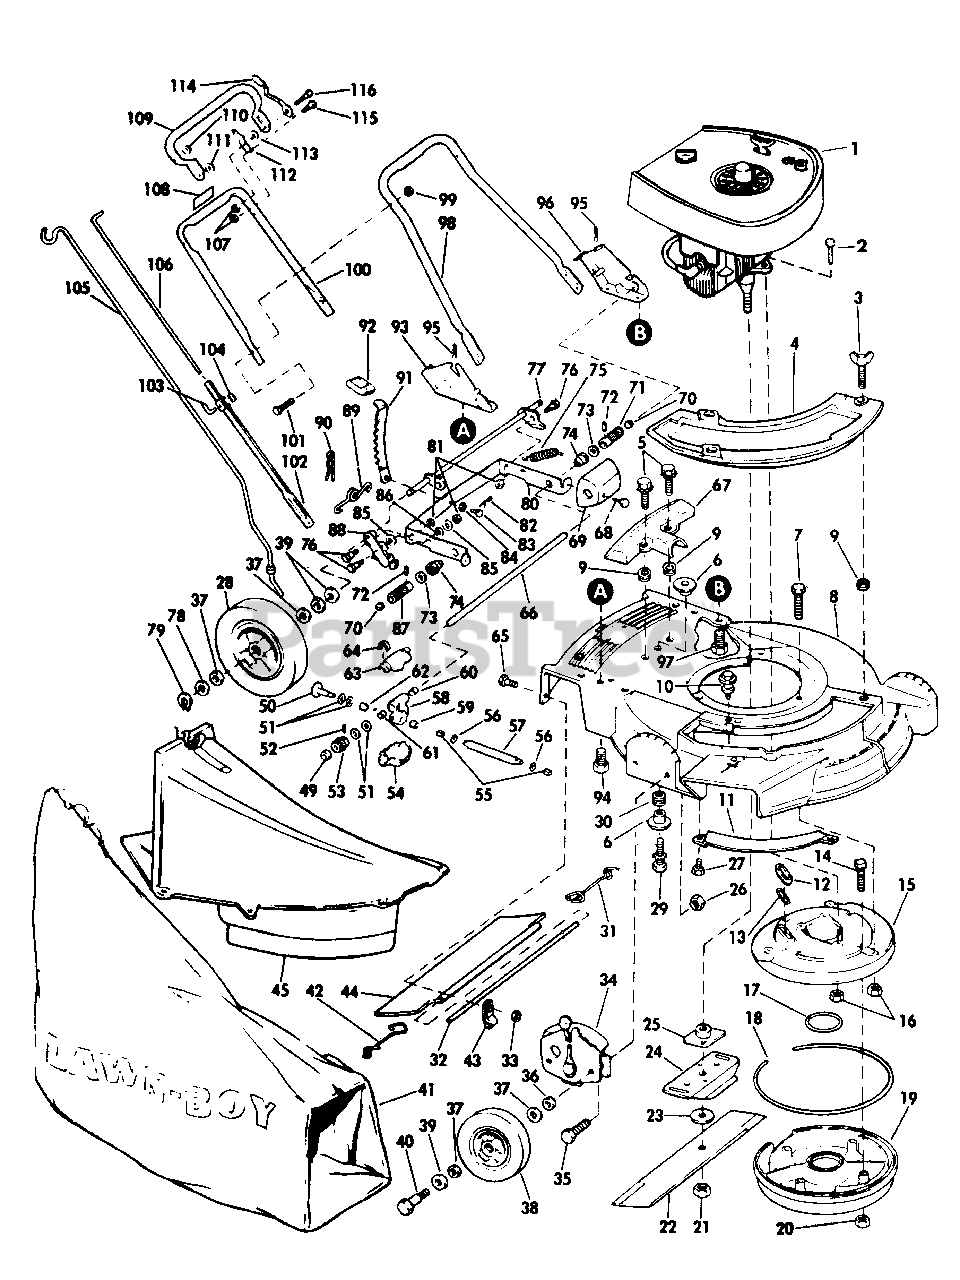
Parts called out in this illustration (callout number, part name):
2	Screw-Crankcase to Muffler Plate
3	Wing Screw
4	Cover Plate
5	Sems Screw-Drive Cover Mounting
6	Spacer-Flanged
7	Screw-Muffler Plate to Housing
8	Housing-21"
9	Grommet
10	Screw
11	Toe Bar
12	Sleeve-Muffler Gasket
13	Gasket-Exhaust
14	Screw-Muffler to Muffler Plate
15	Muffler Plate
16	Nut
17	Gasket-Muffler (inside)
18	Gasket-Muffler (outside)
19	Muffler Cover
20	Nut-Muffler to Muffler Plate
21	Nut-Blade
22	Blade
23	Washer-Blade
24	Stiffener-Blade
25	Collar & Plate Assembly
26	Nut
27	Screw
28	Wheel-Rear
29	Sems Screw
30	Grommet
31	Spring-L.H.
32	Rod
33	Nut
34	Height Adjustment Assembly
35	Screw
36	Washer
37	Washer-Felt
38	Front Wheel
39	Washer
40	Screw
41	Grass Bag
42	Spring-R.H.
43	Clamp
44	Shield Trailing
45	Chute Assembly
49	Washer-Felt
50	Gear-Driver
51	Washer-Thrust
52	Roll Pin
53	Gear-Drive
54	Cover-Gear Bottom
55	Bushing
56	"O" Ring
57	Tube
58	Bracket & Bearing Assembly
59	Needle Bearing-Sealed
60	Needle Bearing-Sealed
61	Needle Bearing
62	Needle Bearing
63	Cover-Gear Top
64	Clamp
65	Screw
66	Shaft
67	Cover-Drive
68	Screw
69	Guard-Roller
70	Plug
71	Drive Roller-L.H.
72	Pin-Spirol
73	Washer
74	Sleeve & Bearing Assembly
75	Spring
76	Bolt-Shoulder
77	Axle Assembly
78	Washer
79	Retaining Ring
80	Bracket
81	Nut
82	Cotter Pin
83	Pin
84	Washer
85	Washer
86	Washer
87	Drive Roller-R.H.
88	Clutch
89	Spring
90	Hairpin
91	Lever
92	Knob
93	Bracket-Handle-R.H.
94	Screw-Handle Bracket
95	Clip
96	Bracket-Handle-L.H.
97	Screw-Handle Bracket
98	Handle-Lower
99	Nut
100	Handle-Center
101	Screw
102	Control Lever Assembly
103	Screw
104	Nut
105	Rod-Grass Bag
106	Control Rod
107	Nut
108	Decal
109	Handle & Grip Assembly
110	Palnut
111	Washer
112	Bracket
113	Washer
114	Spring-Lockout
115	Screw-Stop
116	Bolt-Shoulder
